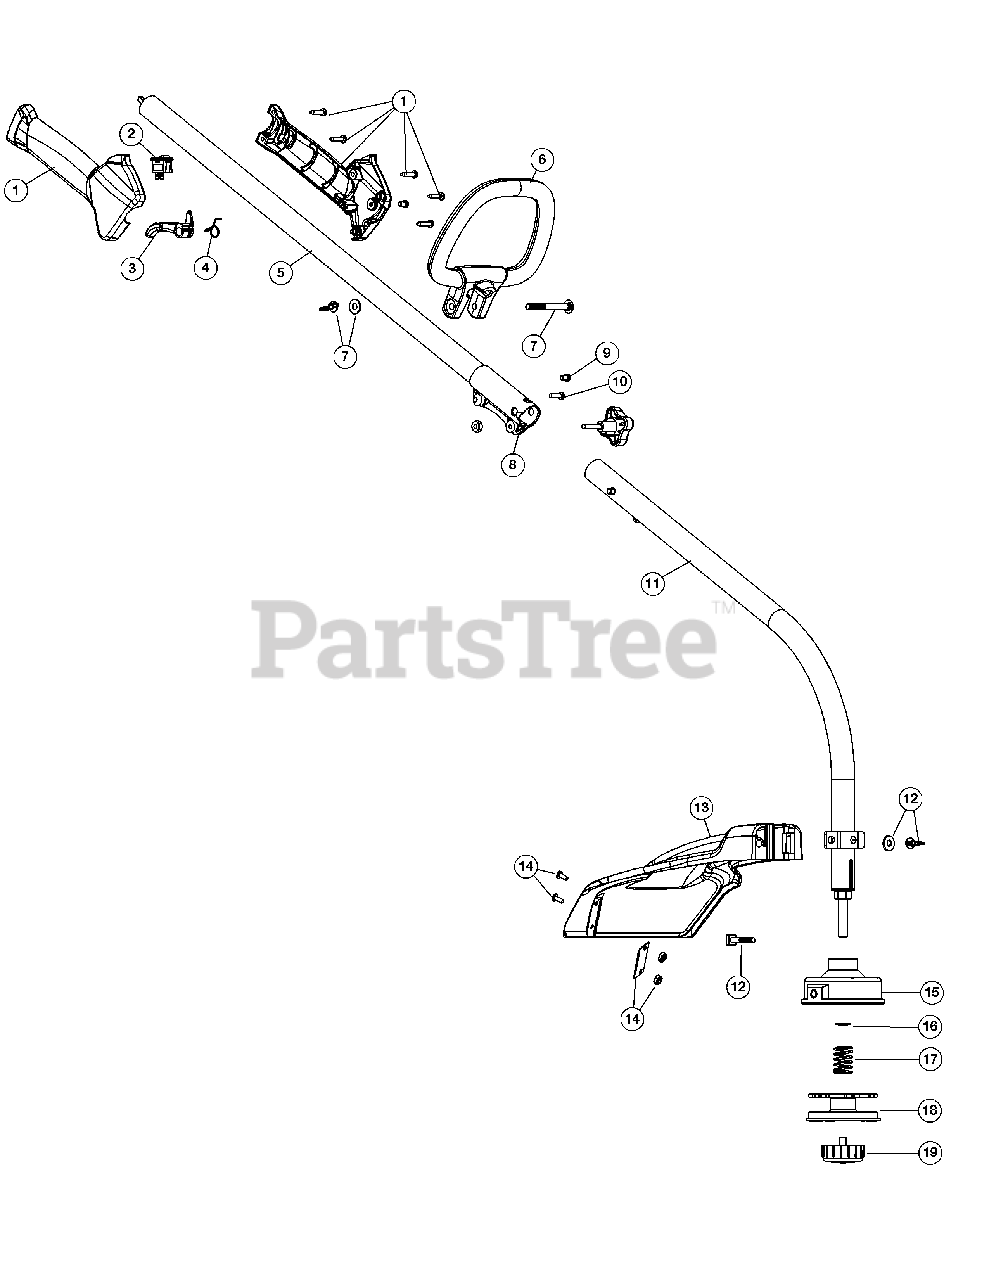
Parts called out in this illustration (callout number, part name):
1	Throttle Housing Assembly (Incl. 2 - 4)
3	Throttle Trigger
4	Throttle Trigger Spring
5	Upper Shaft Housing Assembly
6	D-Handle (Incl. 7)
7	D-Handle Hardware Assembly
8	Split Boom Coupler (Incl. 9 - 10)
9	Anti-Rotation Screw
11	Lower Shaft Housing Assembly
12	Shield Mounting Hardware
13	Shield Assembly (Incl. 14)
14	Blade Assembly
15	Outer Spool Assembly (Incl. 16)
16	Retainer
18	Inner Reel
19	Bump Head Knob Assembly
